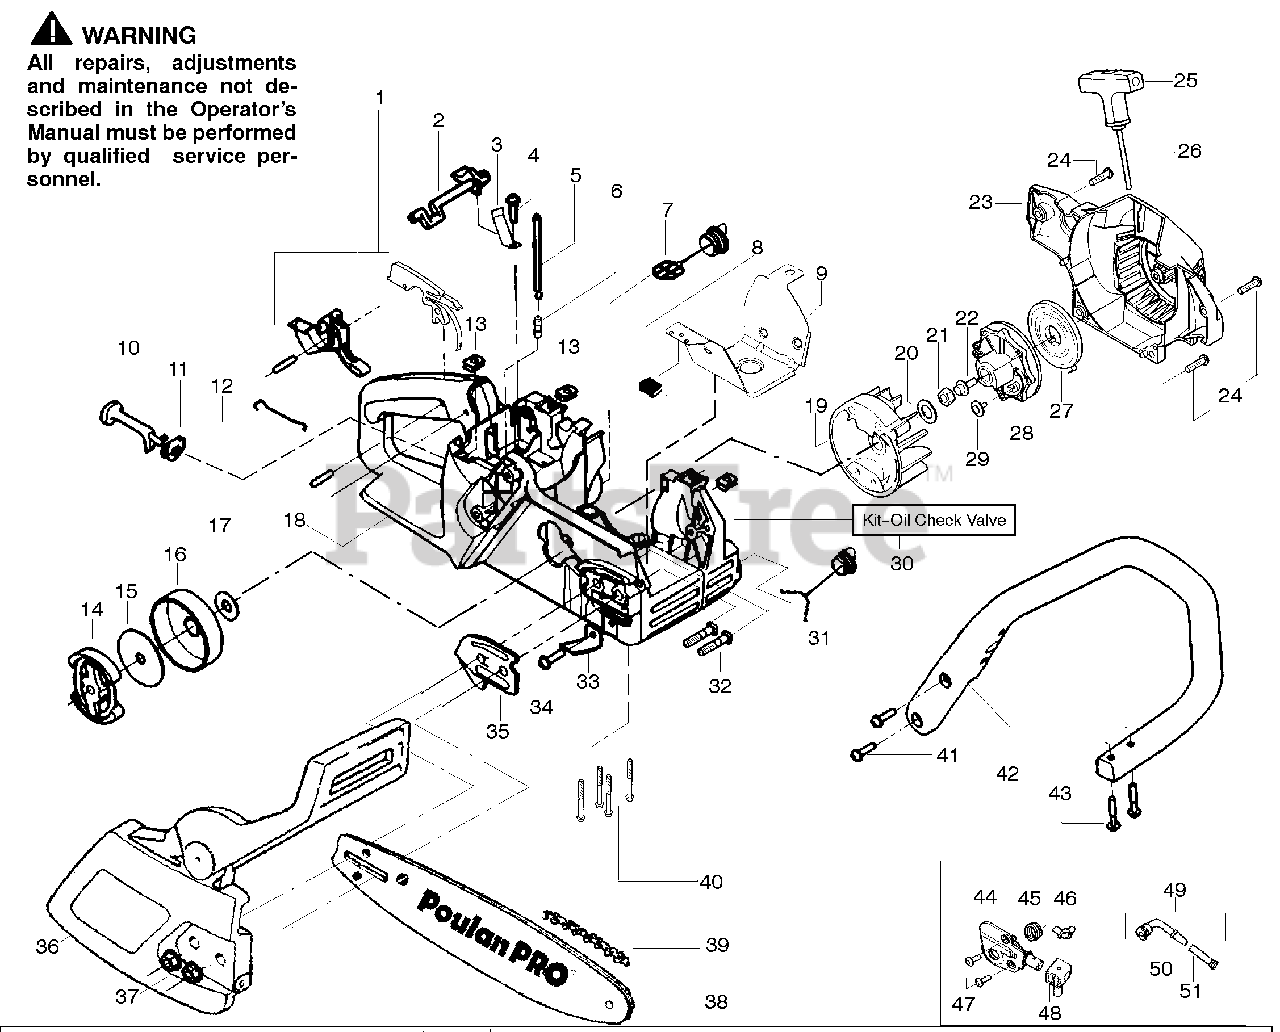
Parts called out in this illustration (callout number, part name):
1	Kit-Trigger & Lockout
2	Lever-Switch
3	Spring-Switch
5	Kit-Fuel Line (Large)
6	Fitting - Fuel line
7	Assy-Fuel Cap w/ret.
8	Clip - "U"
9	Shield - Heat
10	Lever-Choke
11	Grommet-Choke lever
12	Wire-Throttle
13	Nut-Speed
14	Assy.-Clutch
15	Washer-Clutch
16	Assy-Drum W/brg.
17	Washer - Thrust
18	Assy-Chassis
19	Assy-Flywheel
20	Washer-Flywheel
21	Nut-Flywheel
23	Housing-Fan
25	Handle-Starter
26	Kit-Rope
27	Spring-Starter
28	Pulley-Starter
30	Kit-Oil Check Valve
31	Assy-Oil Cap
32	Bolt - Bar
33	Chain Catcher
35	Plate-Bar Mounting
36	Assy.-Chain Brake
37	Nut-Bar Mounting
38	Bar- 18"
39	Chain- 18"
42	Handle-Front
44	Kit-Oil Pump
45	Gear-Worm Spring
46	Elbow-Oil Pickup
48	Block-Seal
49	Assy-Oil-Pickup
50	Pickup-Oiler
51	Filter-Oil
